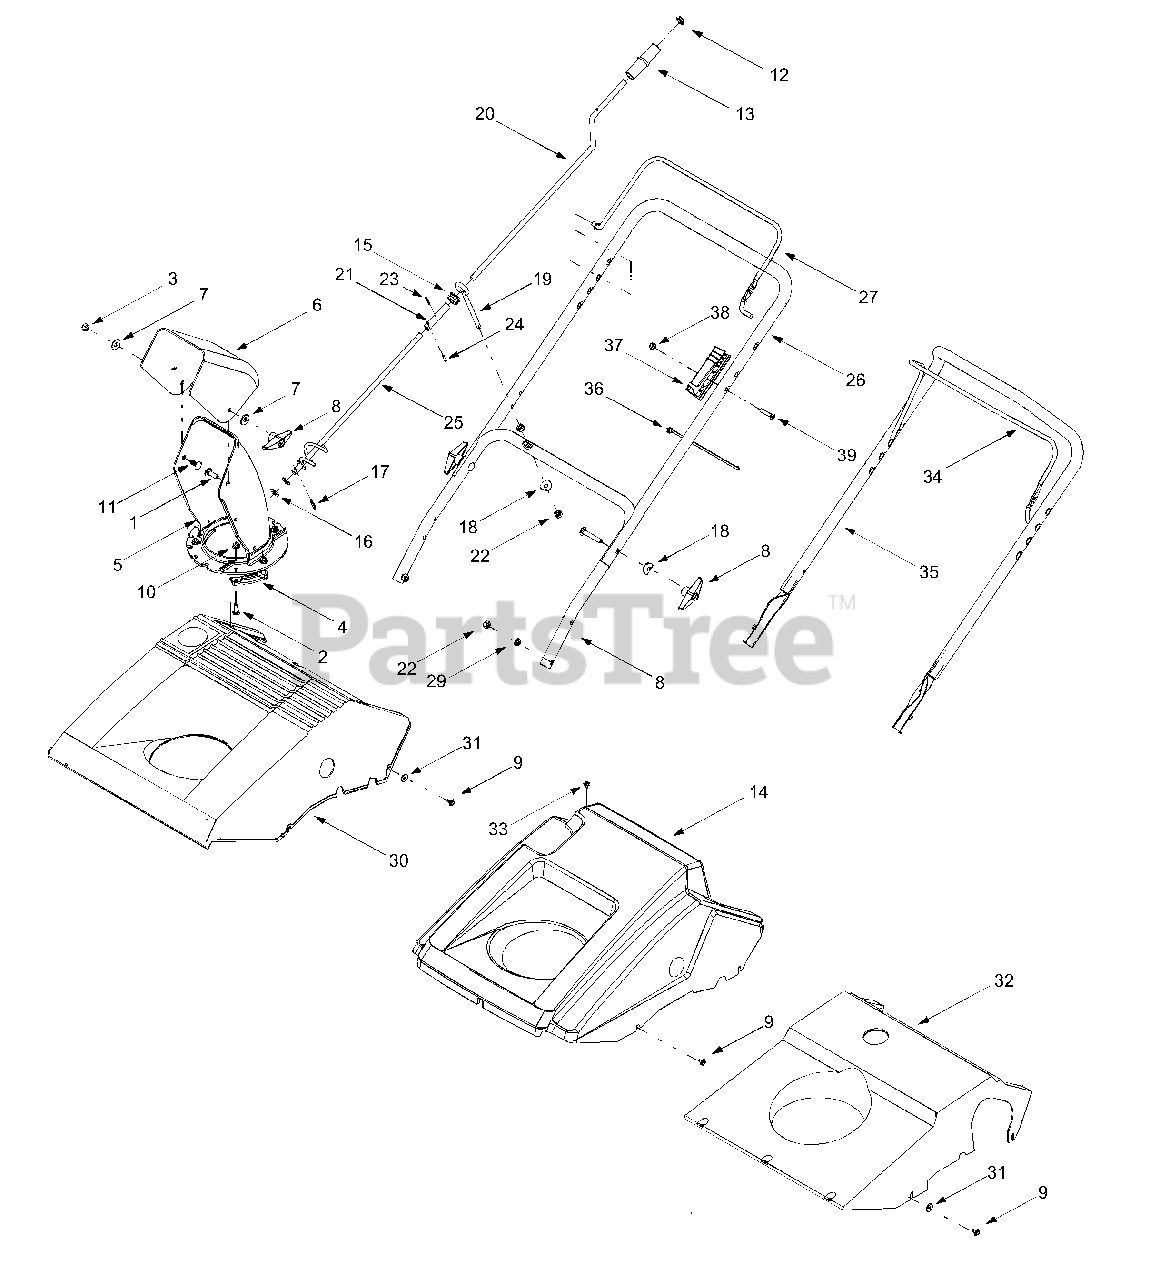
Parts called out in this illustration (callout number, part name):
1	Splined Carriage Screw, 5/16-18 x 1.0
2	Hex Cap Screw, 1/4-20 x.75
3	Hex Lock Nut, 5/16-18
4	Chute Flange Keeper
5	Lower Chute, 5.0
6	Upper Chute, 5.0
7	Washer, .349 x .879 x .063
8	Wingnut Knob, 5/16-18
9	Screw, #10-16 x .375
10	Hex Flange Lock Nut, 1/4-20
11	Carriage Bolt, 5/16-18 x .75
12	Push Cap, 3/8
13	Knob, 1.0 x 3.2
15	Rubber Grommet, .44 x .94 x .50
16	Flat Washer, .375 x .738 x .063
17	Internal Cotter Pin, .072 x 1.12
18	Saddle Washer, .320 x .93
19	Eyebolt, .70
20	Upper Chute Crank
21	Spacer, .382 x .50 x 1.12
22	Hex Nut, 5/16-18
23	Cotter Pin, 3/32 x .75
24	Rolled Pin, 1/8 x .63
25	Chute Crank Assembly
29	Lock Washer, 5/16
31	Flat Washer, .194 x .62 x .063
32	Shroud, Black
33	Screw, #10-16 x .625
36	Cable Tie
37	Control (Cable) Housing
38	Nylon Hex Lock Nut, 1/4-20
39	Machine Screw, 1/4-20 x 1.31
